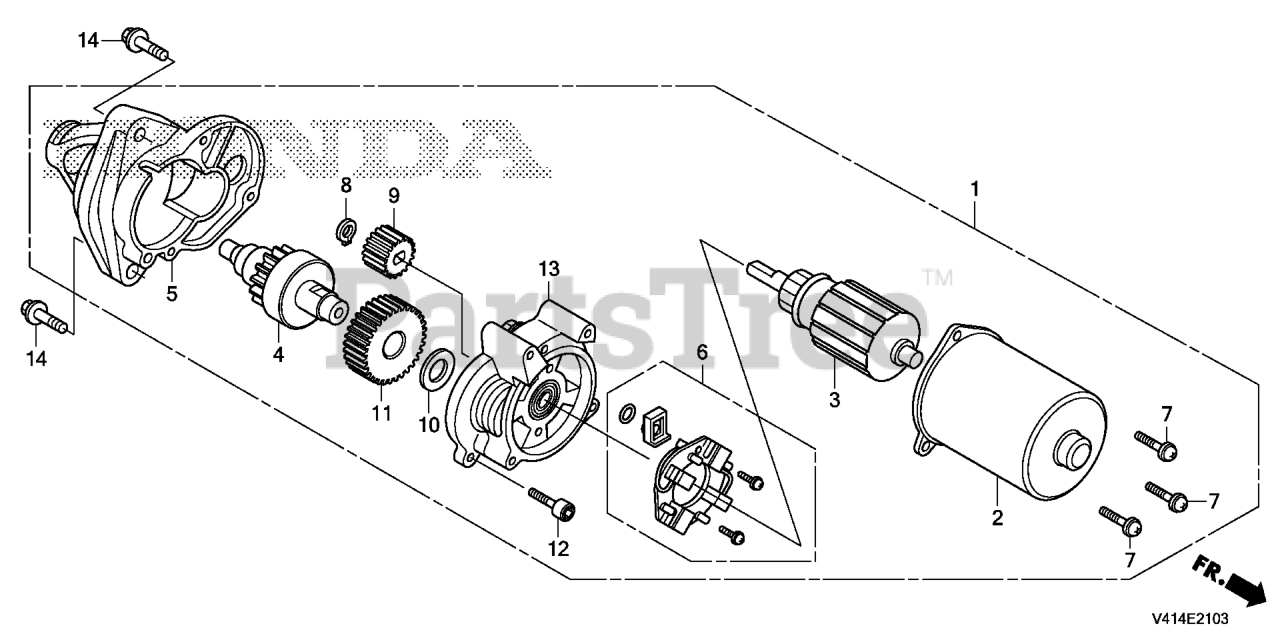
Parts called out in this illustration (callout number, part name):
1	STARTER MOTOR UNIT
2	HOUSING ASSY.
3	ARMATURE ASSY.
4	GEAR ASSY., DRIVE
5	CONE ASSY., NOSE
6	BOARD ASSY., BRUSH
8	RING, RETAINER
13	BRACKET ASSY.
14	BOLT, FLANGE (8X40) Use up to Engine SN 1003236.
